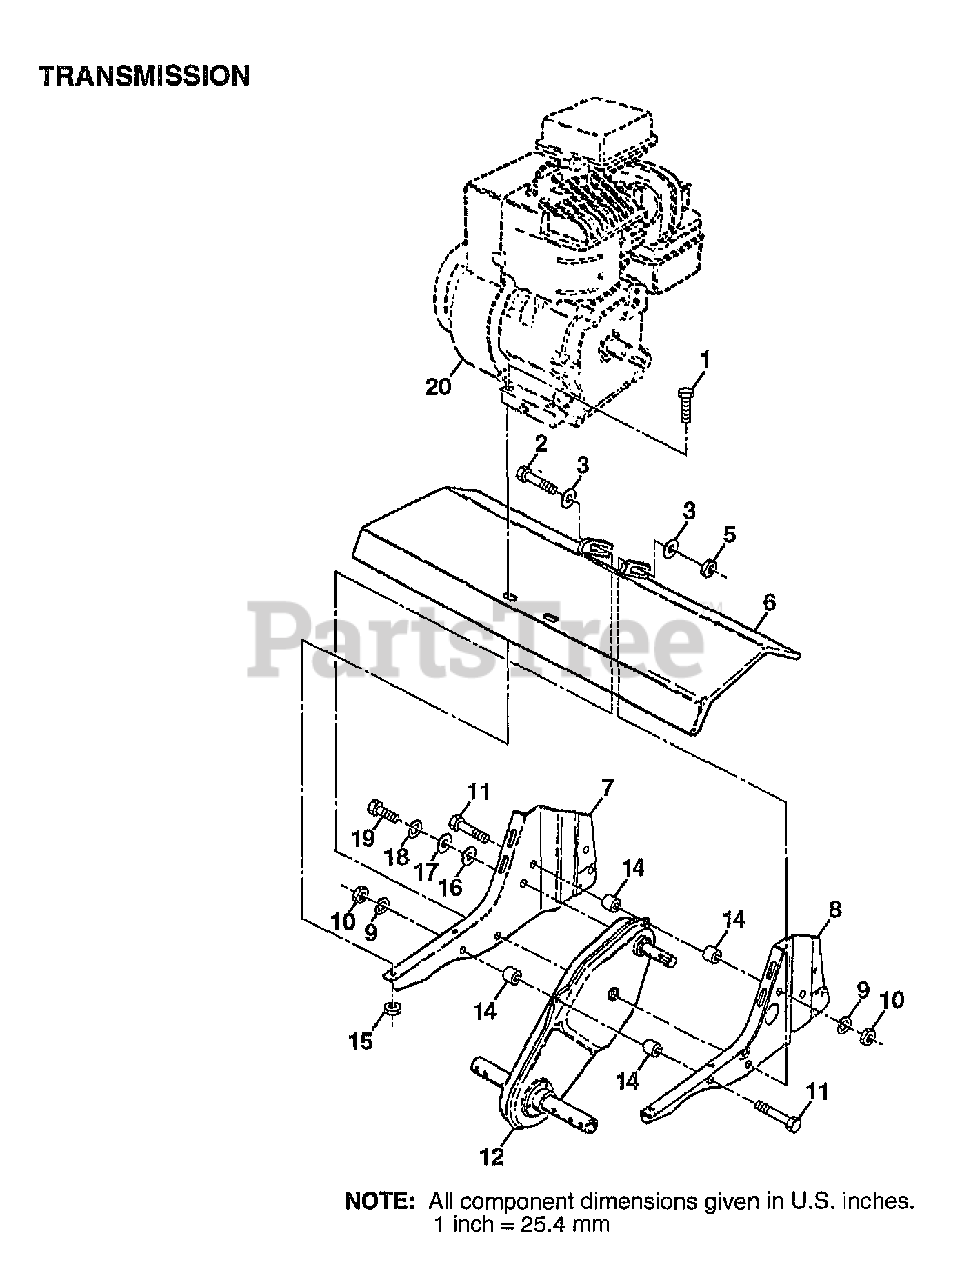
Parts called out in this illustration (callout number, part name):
1	BOLT.HEX.5/16-1.5
2	BOLT HEX 3/8-16
3	WASHER
5	NUT
6	SHIELD.PNT.TINE
8	ENGINE BRKT LH TI
9	LOCKWASHER
10	NUT.HEX.5/16-18
14	SPLIT SPACER RT
16	WASHER
17	WASHER
18	LOCKWASHER
19	BOLT
